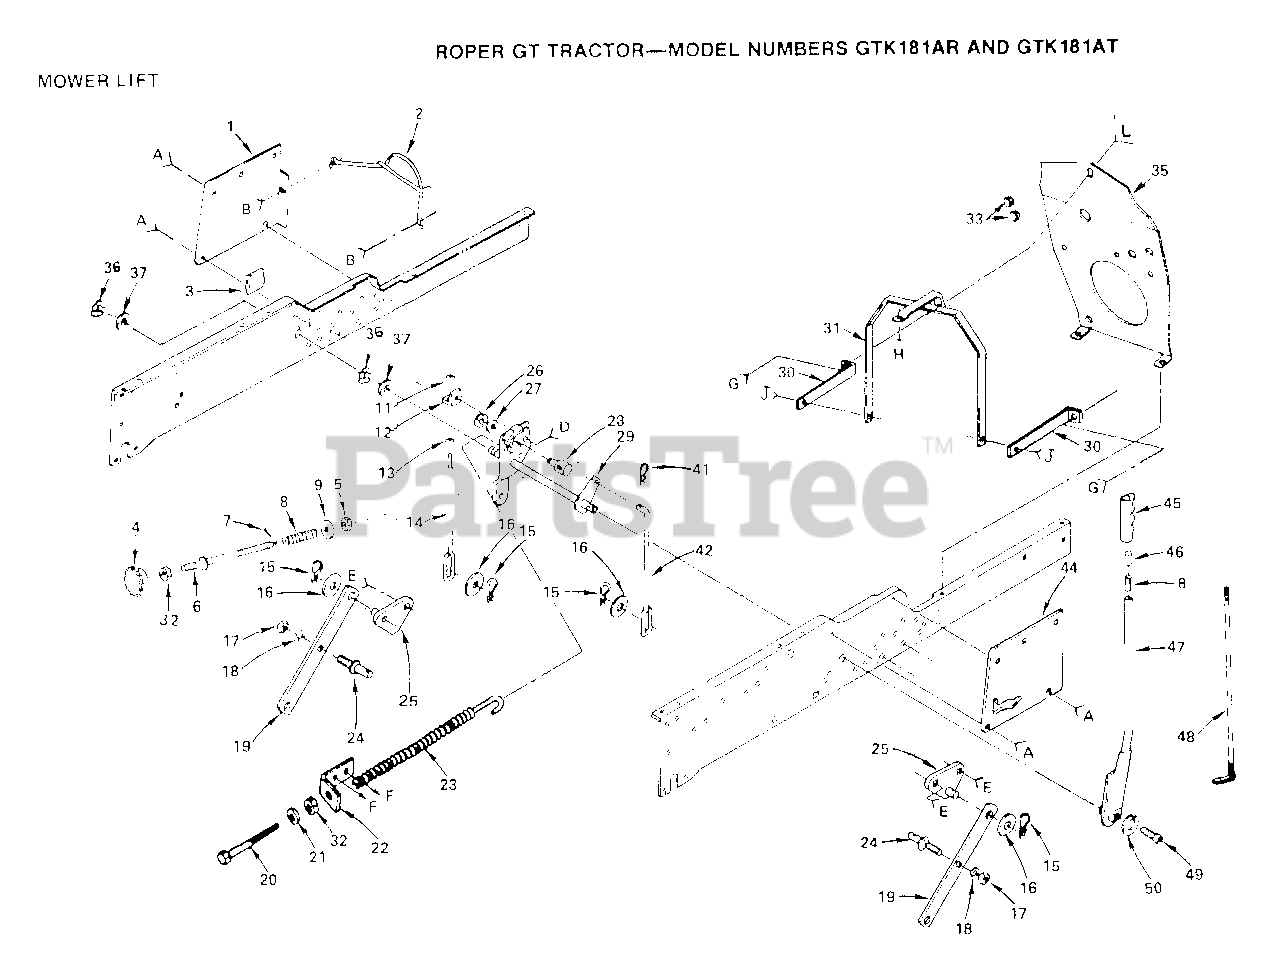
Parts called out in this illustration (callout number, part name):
5	NUT T
6	ROD ADJ. T
8	SPRING T
9	WASHER
11	NUT
12	BRACKET T
13	NUT.HEX.3/8-16UNC
14	LINK-LIFT MOW T
15	SPRING H
17	NUT
18	LOCKWASHER
19	SUSPENSION ARM GT
20	BOLT-ADJ SPRING T
21	WASHER
24	PIVOT STUD GT
25	SUSP BRACKET T
26	KLIP RING
27	WASHER
28	TRUNION LT
30	BRACKET T
32	NUT
36	E-RING
37	WASHER
42	LIFT LINK RH T
45	GRIP
48	LEVER ROD LT
49	"BOLT,HEX"
50	LOCKWASHER
